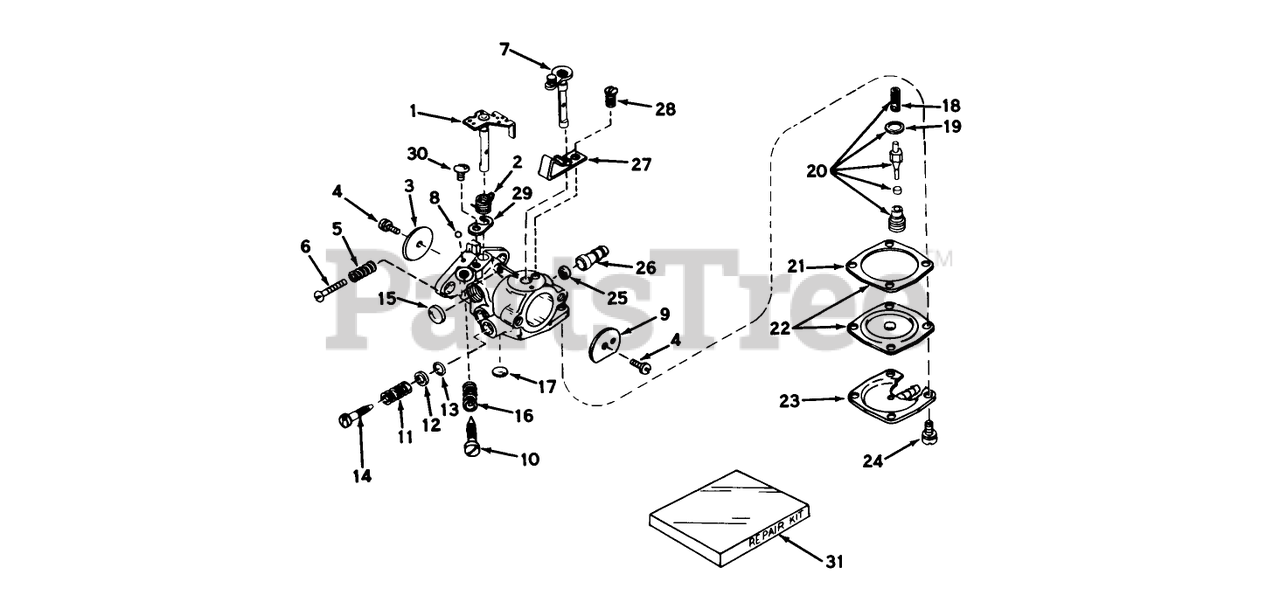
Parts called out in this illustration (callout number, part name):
1	Shaft Lever Assy., Throttle
1	Dust Cover Spring
2	Spring Return
2	Dust Cover
3	Shutter, Throttle
3	Dust Cover Gasket
4	Screw-Shutter
4	Hose-Primer 209543
5	Spring-Tension
5	Coil Assy.
6	Screw-Throttle Crack Screw / Idle Speed
6	Gasket 209542
7	Shaft Lever Assy., Choke
7	Condenser Screw
8	Shot, Lead
8	Condenser Assy.
9	Sealing Washer
10	Screw, Idle Adjustment
10	STRAP S
11	Spring
11	RETAINER WASHER
12	Washer
12	Fuel Hose
13	ORing
13	Fuel Tank
14	Screw Main Adjustment
14	Flatwasher
15	Plug-Welch, Idle Mixture Well
15	Washer
16	Spring, IdleAdjustm. Screw
16	DECAL
17	Plug Welch
17	Cam Felt
18	Spring-Valve
19	Gasket-Valve Seat
20	Inlet Needle, Seat, Spring Gasket Assy. (Incl. Nos. 18 19)
21	Gasket-Diaphragm
22	Diaphragm Ass. (Incl. No. 21)
23	63561/33165A O"HITC
24	Screw, Diaphragm Cover
25	Valve Check
26	Fitting, Fuel inlet
27	Spring, Detent
28	Screw Detent spring
29	Retainer, Throttle Shaft
30	Screw Detent spring
31	Repair Kit
